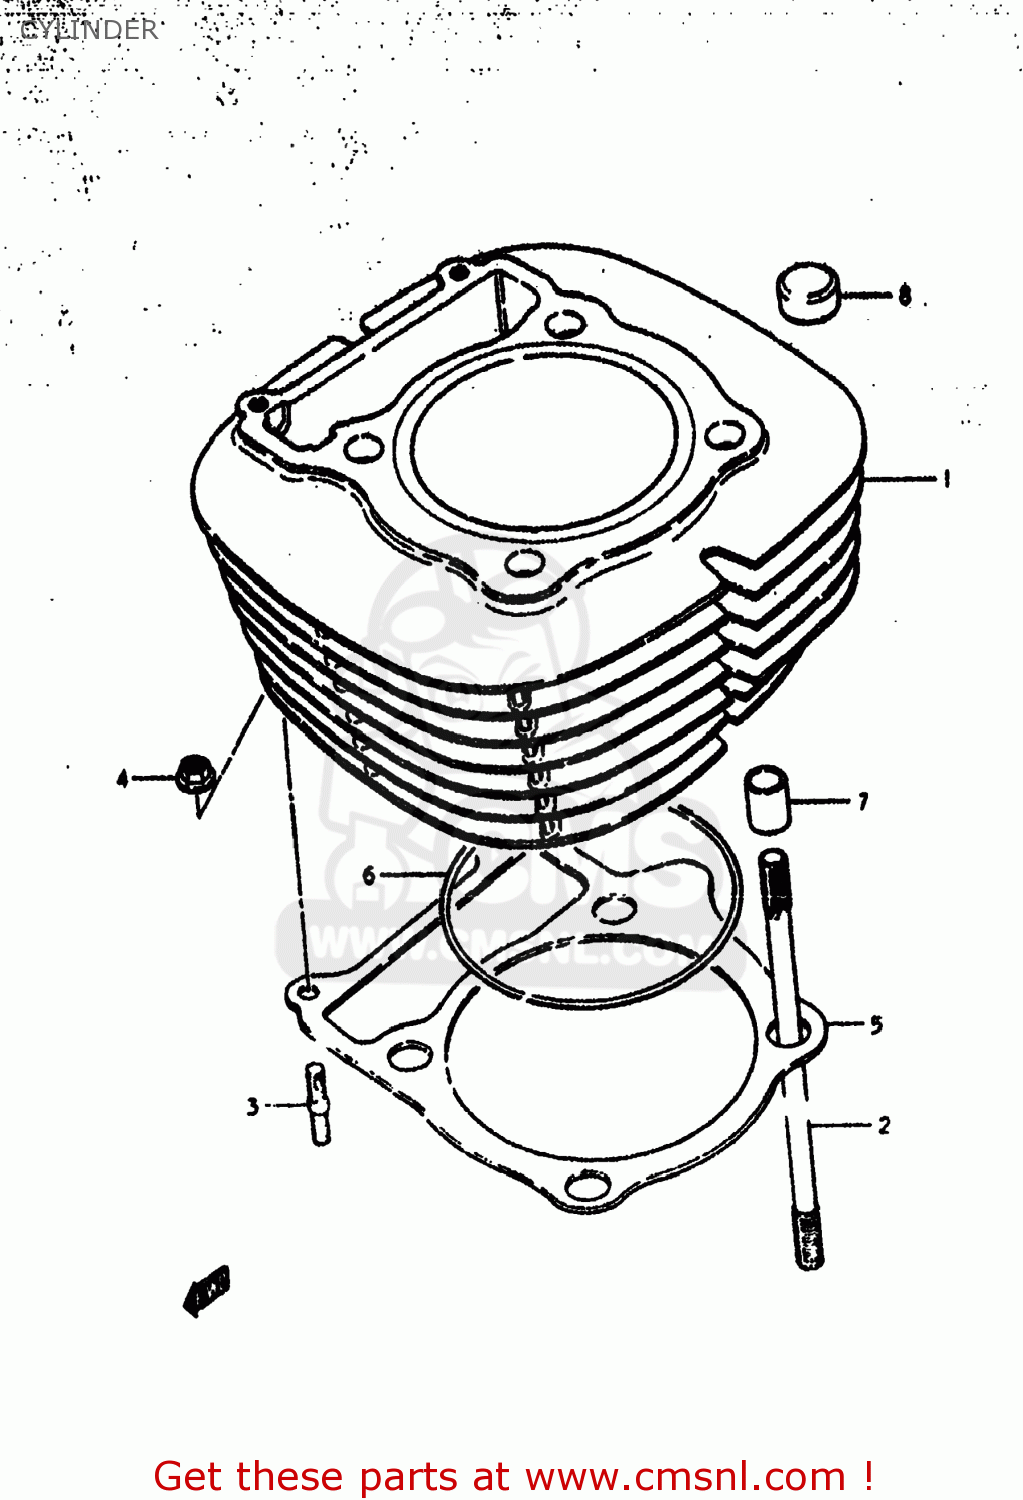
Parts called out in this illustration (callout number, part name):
1	CYLINDER
2	STUD
3	STUD 6X20
4	NUT
5	GASKET,CYLINDER (MCA)
6	O RING(D:2,ID:87)
7	PIN
8	PAD,CYLINDER HEAD
9	PAD,CYLINDER HEAD
